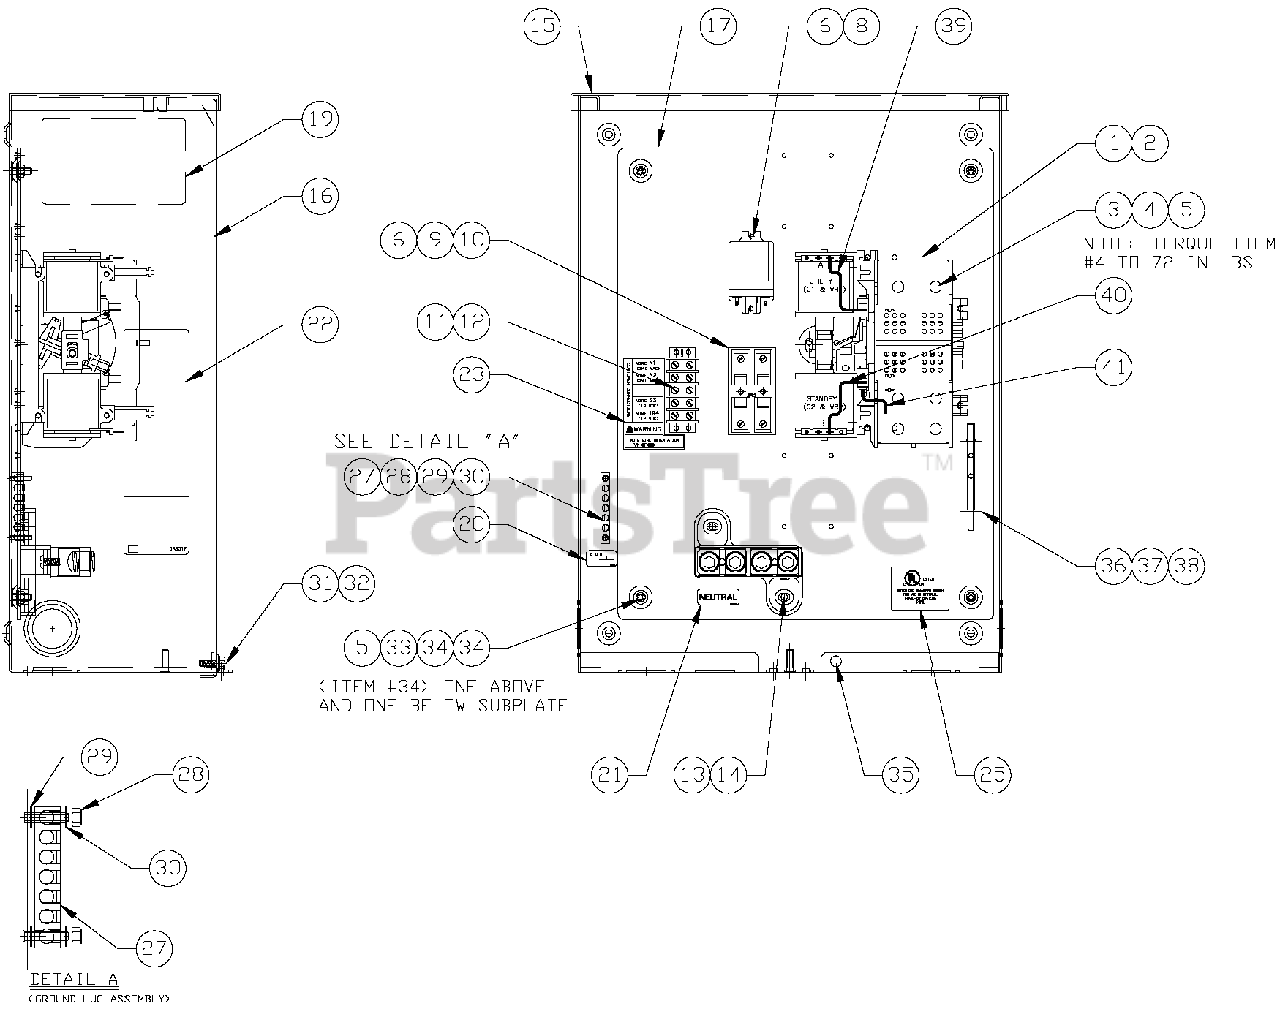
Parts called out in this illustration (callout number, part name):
1	XFRSW HSB 200A 2P 250V
2	SCREW HHTT M5-0.8 X 10 BP
3	LUG SLDLSS 250-#6 AL/CU
4	SCREW BHSC 1/4-20 X 3/8
5	WASHER LOCK M6-1/4
6	SCREW HHTT M4-0.7 X 10 BP
8	RELAY PNL 12VDC DPDT
9	FUSEBLOCK 30A 600V 2 POLE
10	FUSE 5A X BUSS HLDR73591
11	BLOCK, TERM 20A 5 X 6
12	RIVET, POP .156 X .67
13	ASSY NEUTRAL BL150-200A
14	SCREW HHTT M6-1.0 X 12 MM
15	ENCLOSURE, 100/200A TRANSFER SWITCH
16	COVER, TRANSFER SWITCH
17	SUBPLATE, 100/200A XFER SW
19	DECAL,XFER SW NON 200A 120/240
20	DECAL, GROUNDING LUG
21	DECAL, NEUTRAL
22	DECAL, MANUAL 5A FUSE
23	DECAL, TERMINAL STRIP
25	DECAL, UL LIST HSB
26	DECAL, LIVE CIRCUIT ENG/FRN/SPN
27	GROUND BAR (5) 4-14 AWG CONN
28	NUT HEX LOCK M4-0.7 SS NYL INS
29	WASHER SHAKEPROOF EXT #8 STEEL
30	WASHER FLAT M4
31	SCREW HHC 1/4-20 X 1/2 SS
32	WASHER M6 NYLON INT HEX
33	NUT HEX 1/4-20 SS
34	WASHER FLAT 1/4-M6 ZINC
35	NUT TRIC 1/4-20 X .525
36	BRACKET, ARM EXTENDER
37	ARM EXTENDER PIN
38	RIVET POP .156 X .362 AL
41	WIRE-E1
42	STRAIGHT SPADE CONNECTOR
